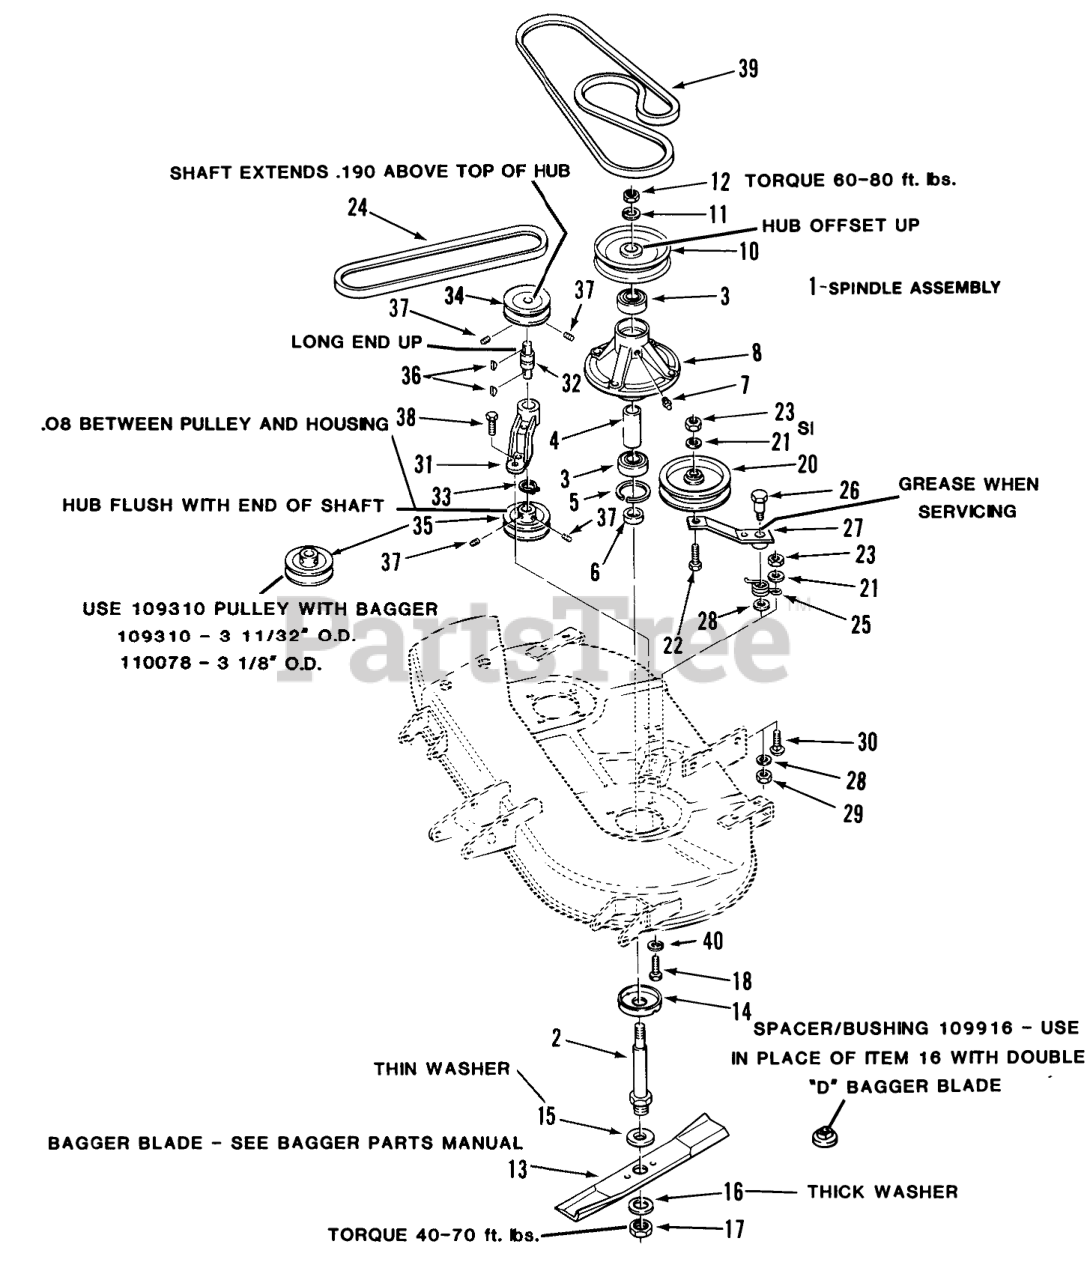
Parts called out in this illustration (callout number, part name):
1	Spindle Assembly, (includes parts 2 to 8 & 14)
2	SHAFT SPINDLE
3	BEARING-BALL
5	Ring-Snap
6	SPACER-BLADE
7	Fitting-Grease
8	HOUSING SPINDLE
10	PULLEY BLADE
11	Lockwasher
12	Jam Nut
13	ASSY BLADE KIT
14	CUP-SPINDLE
15	Washer
16	Washer
17	Nut-Jam
18	BOLT
20	Idler Pulley
21	Washer
22	Bolt
23	NUT
24	V-BELT DRIVE
25	SPRING-TORSION
26	BOLT-SHOULDER
27	Idler Arm
28	WASHER
29	NUT-JAM(7/16-14)
30	Bolt
31	Jack Shaft Housing
32	BRG INTEGRAL SHAFT
33	Snap Ring
34	PULLEY
35	PULLEY-LOWER
36	KEY-WOODRUFF
37	Set Screw
38	Bolt
39	V-BELT
40	LOCKWASHER
